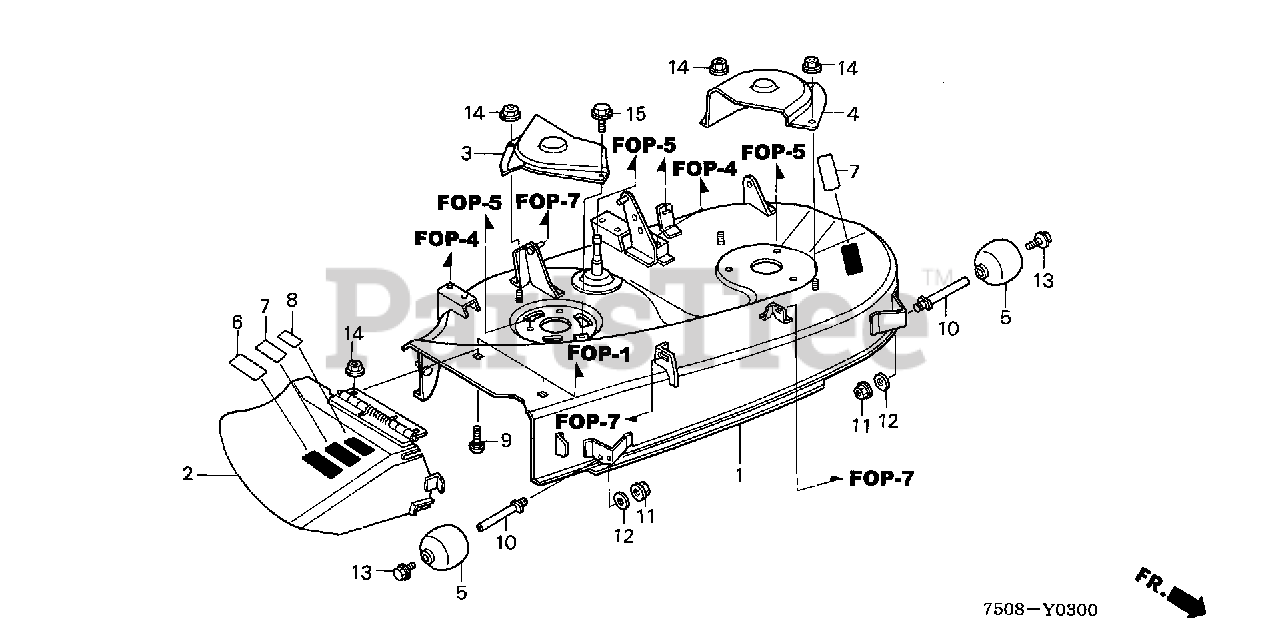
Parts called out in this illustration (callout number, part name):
1	HOUSING, CUTTER (NOT AVAILABLE)
2	ADAPTER, DISCHARGE *NH190M* (VINTAGE GRAY METALLIC)
3	COVER, R. BELT *NH190M* (VINTAGE GRAY METALLIC)
4	COVER, L. BELT *NH190M* (VINTAGE GRAY METALLIC)
5	ROLLER, ANTI-SCALP
6	LABEL B, WARNING (ENGLISH)
7	LABEL A, WARNING (ENGLISH)
8	MARK, INCH SIZE (38)
9	BOLT, SPECIAL (9X15)
10	SHAFT, ANTI-SCALP ROLLER
11	NUT, SELF-LOCK (12MM)
12	WASHER, THRUST (12MM)
13	BOLT-WASHER (8X16)
14	NUT, FLANGE (8MM)
15	BOLT, FLANGE (8X14)
